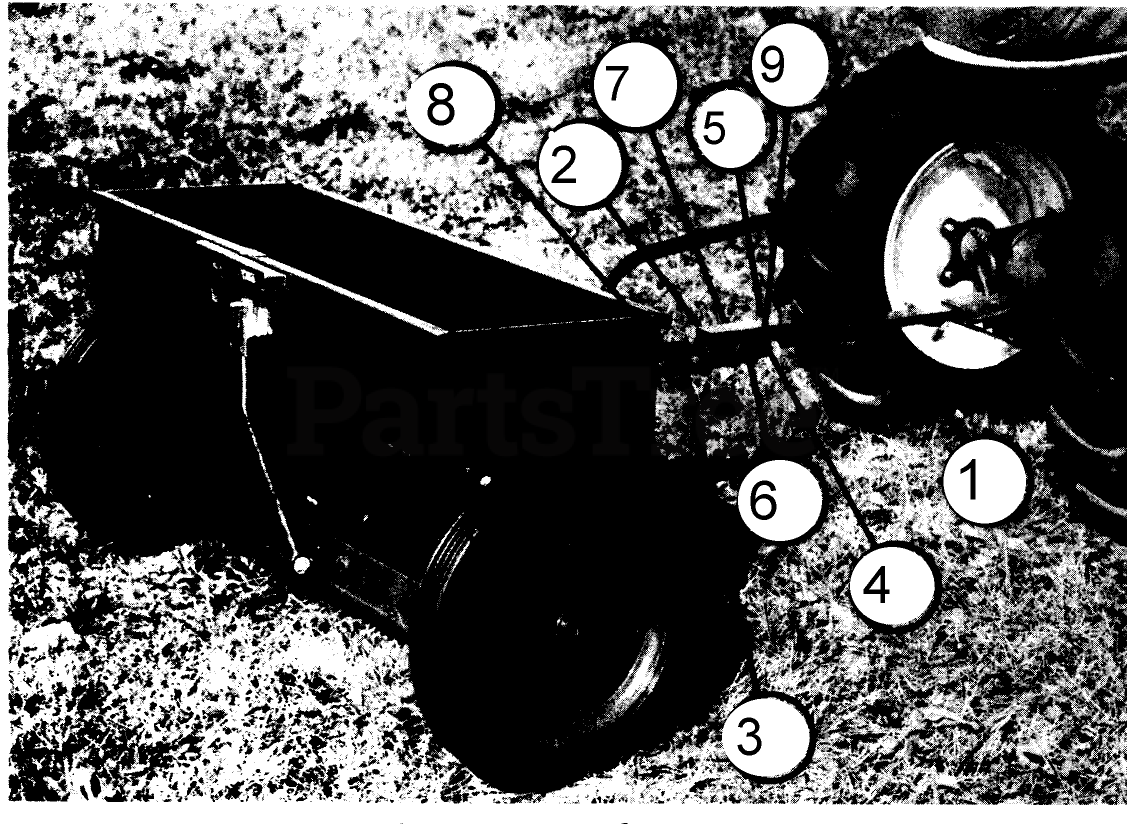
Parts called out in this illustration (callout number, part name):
1	Tongue
2	Swivel Assembly
3	Rod Assembly
4	Cap Screw, 1/2-13 x 1 3/4
6	Hex Head Cap Screw
7	Hex Nut
8	Washer
9	Hitch, complete Agitator and Axle, pair Axle Support and Bearings Axle Bearings, pair Baffle Plate Bearing Retainer and Plate Connecting Rod Control Rod Housing Green Knob for Control Plate Handle Brace, each Hopper, body only Operating Lever with Kn
